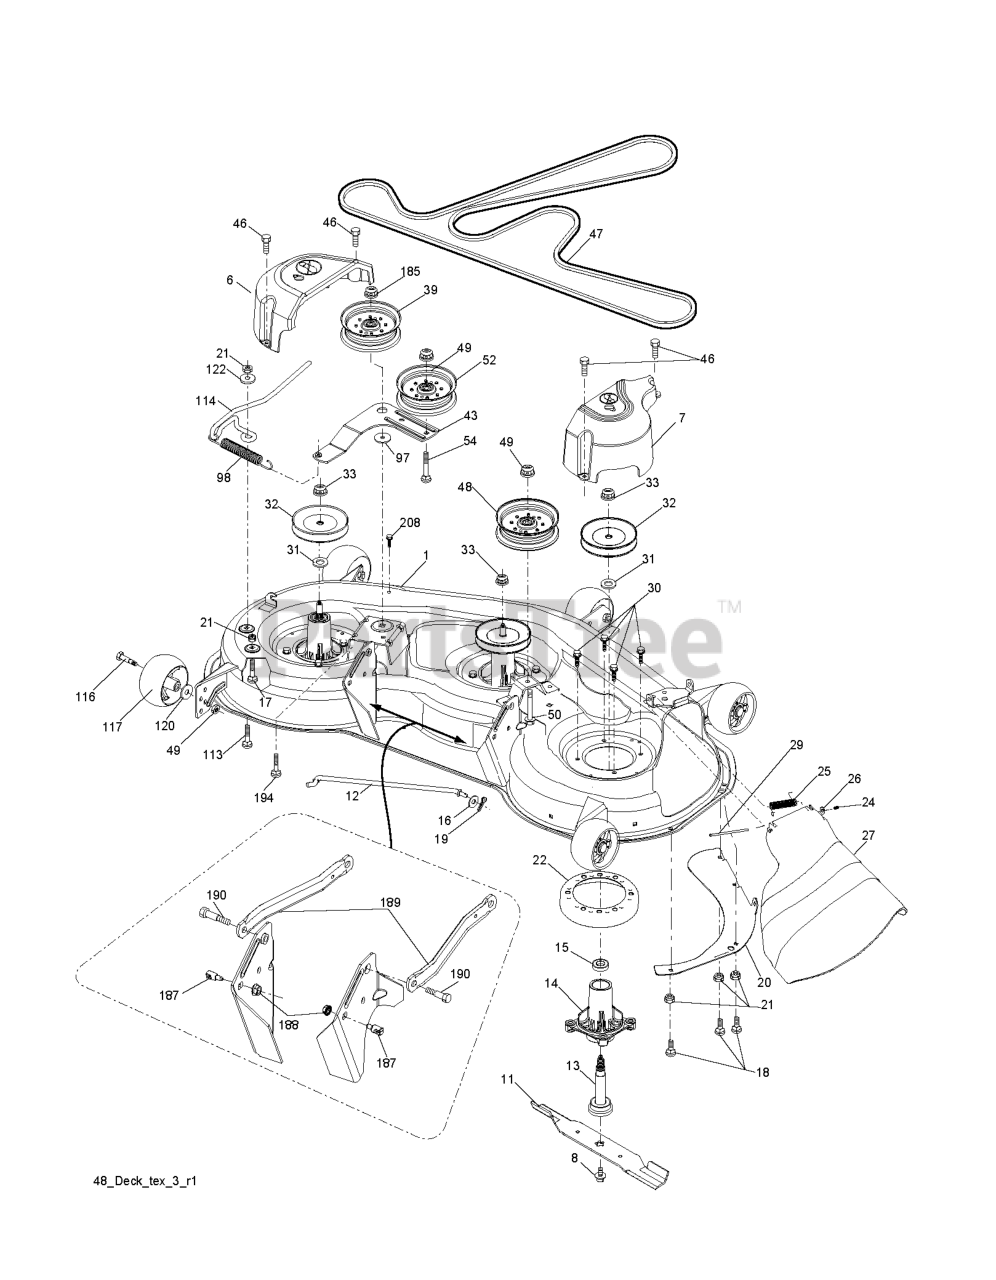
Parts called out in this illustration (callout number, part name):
1	DECK.WELDMENT.48"2006
6	COVER.MANDREL.LH.48"(2 2)
7	COVER.MANDREL.RH.48"
8	BOLT 7/16 ASM BLADE
11	48" HI-LIFT BLADE
12	ROD.ANTI.SWAY.48/54"TE
13	SHAFT ASM MANDREL
14	RP.HOUSING.MANDREL.4PT.
16	WASHER
17	BOLT.CARR.5/16-18X5/8.SHORT
18	BOLT
19	PIN.COTTER.5/16.BOW TI
20	BAFFLE, VORTEX MWR
21	LOCKNUT
22	STRIPPER.MANDREL.ROUND.BLACK
24	CAP-SLEEVE LT
25	SPRING, TORSION
26	NUT PUSH M
27	DEFLECTOR SUBS TO 532 180655
29	ROD.HINGE
30	SCREW, WASHER HEAD
31	WASHER.SPACER.MANDREL
32	PULLEY MANDREL
33	NUT.FLANGE.LOCK.TOP
39	RB PULLEY.IDLER.4.50/HUB SPEC
46	SCREW.1/4-20X5/8
47	BELT.DRIVE.DECK
48	PULLEY.IDLER.48"PRIMARY
49	NUT LOCK FLG 3/8-16 UNC
50	SCREW TT 3/8-16X2-1/4 UNC
52	PULLEY.IDLER.2006
54	BOLT.3/8-16X1.50
98	SPRING, DECK DRIVE
114	ROD.TENSION.RELIEF.TEX (2 2)
116	BOLT.SHOULDER.3/8-16X3-5/8.
117	RP WHEEL. GUAGE RALLY
120	WASHER
122	BUSHING.RELIEF.TENSION
185	NUT.LOCK.FLANGE.7/16
187	STUD.FASTNER.W/ANTI-ROTATE
188	NUT LOCK HEX FLANGE 5/16-18
189	ARM.SUSPENSION.MOWER
190	BOLT.SHOULDER
194	BOLT.CARR.SQNK.7/16
208	SCREW 3/8-16X1/2
